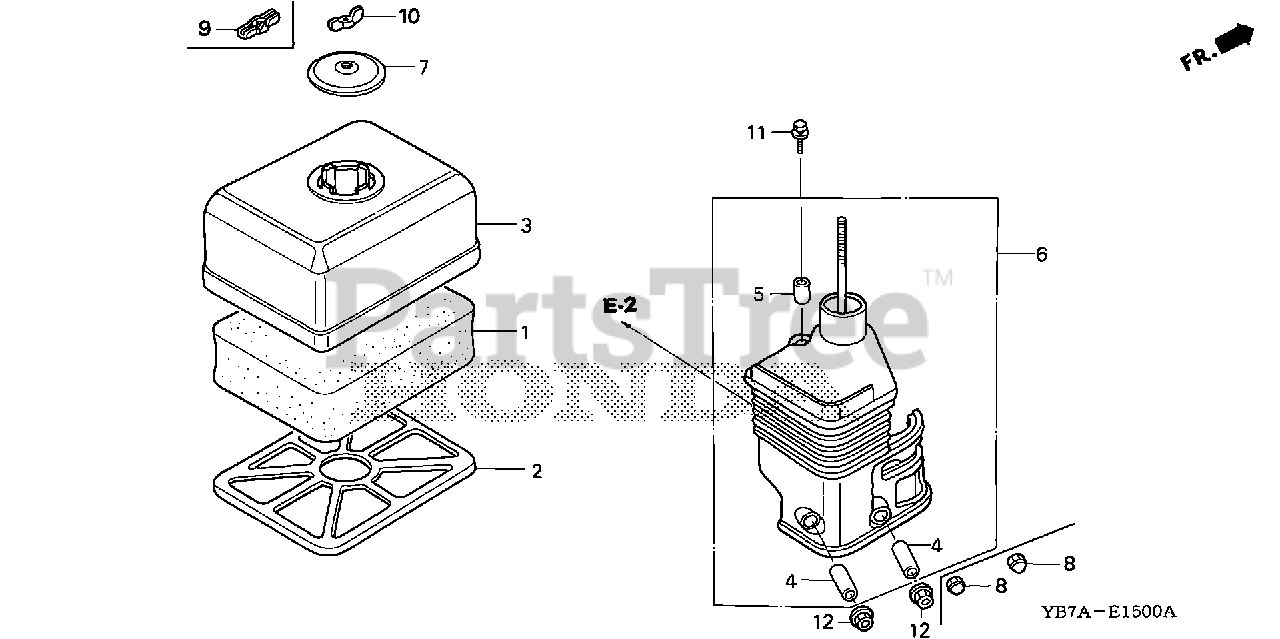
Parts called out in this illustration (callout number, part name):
1	ELEMENT, AIR CLEANER (SEMI-DRY)
2	GRID, AIR CLEANER (SEMI-DRY)
3	COVER, AIR CLEANER (SEMI-DRY)
4	COLLAR, AIR CLEANER
5	COLLAR B, AIR CLEANER
6	ELBOW, AIR CLEANER
7	CAP, CLEANER
8	NUT, CAP (6MM)
9	NUT, AIR CLEANER COVER (DACRO COATING)
11	BOLT-WASHER (6X20)
